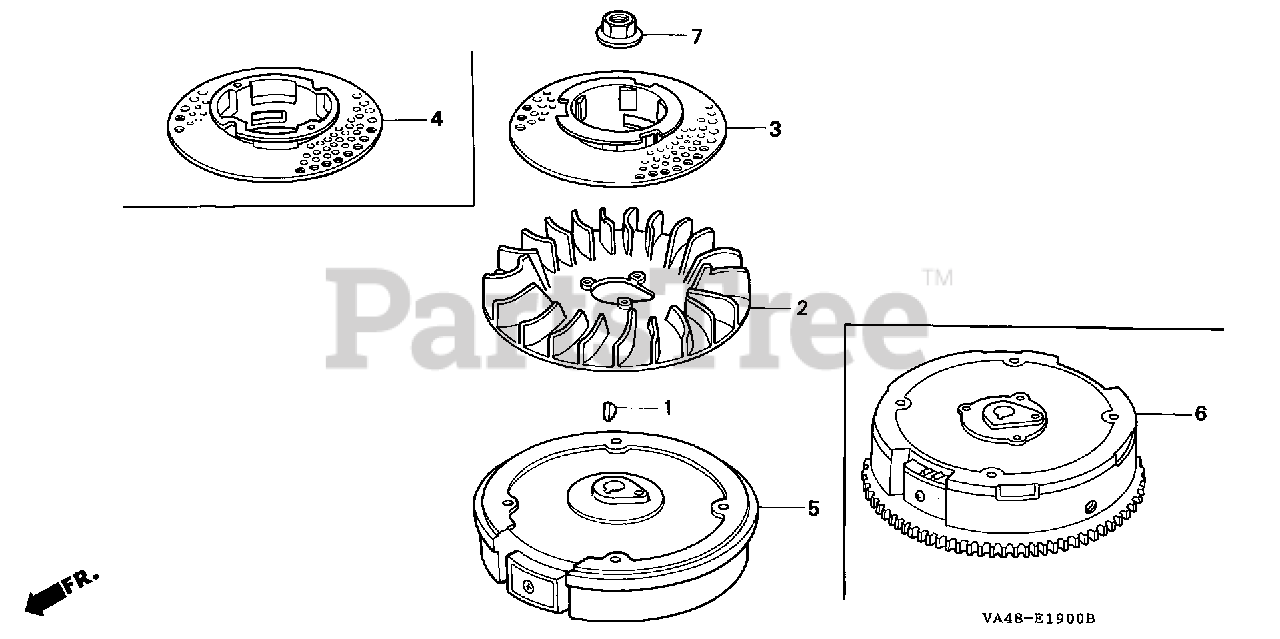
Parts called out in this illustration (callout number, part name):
1	KEY, SPECIAL WOODRUFF (25X18)
2	FAN, COOLING (USA)
3	PULLEY, STARTER
4	PULLEY, STARTER
5	FLYWHEEL
7	NUT, SPECIAL (14MM)
